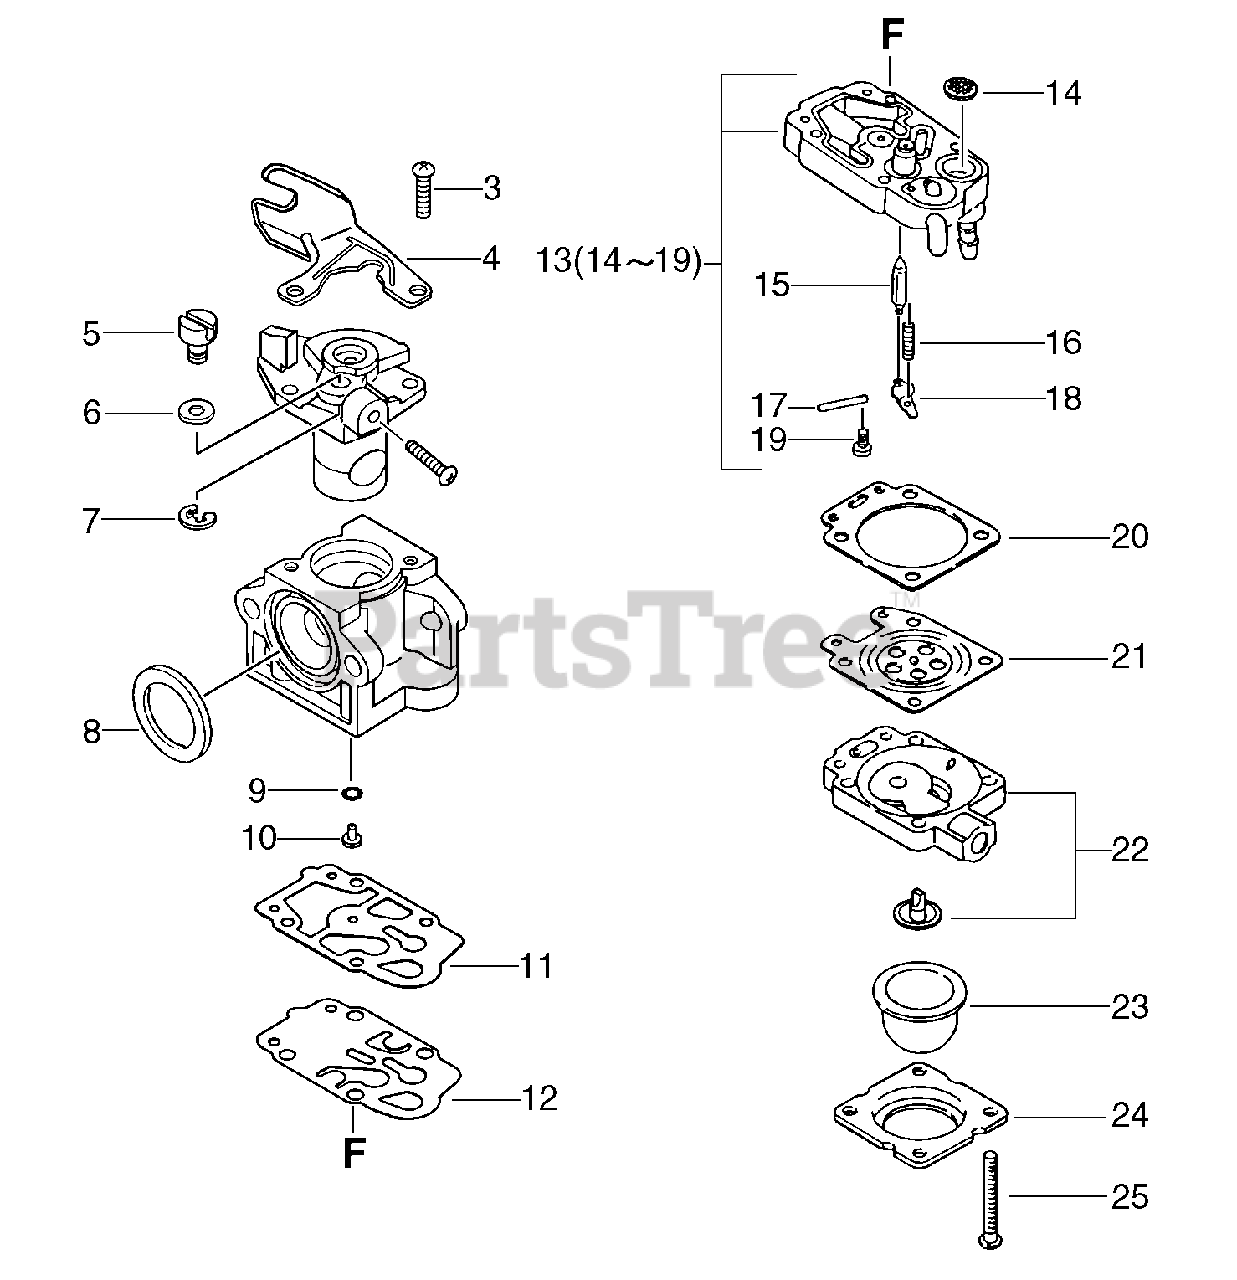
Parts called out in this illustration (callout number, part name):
4	BRACKET, CABLE
7	RING, RETAINING
9	O-RING
10	JET
11	GASKET, PUMP
12	DIAPHRAGM, PUMP
13	PUMP BODY ASSY
14	STRAINER
15	VALVE, INLET NEEDLE
16	SPRING, METERING LEVER
17	PIN, METERING LEVER
18	LEVER, METERING
19	SCREW, METERING LEVER PIN
20	GASKET, METERING
21	DIAPHRAGM, METERING
22	PURGE BASE ASSY
23	BULB, PURGE
24	RETAINER, PURGE BULB
25	SCREW, PUMP COVER
